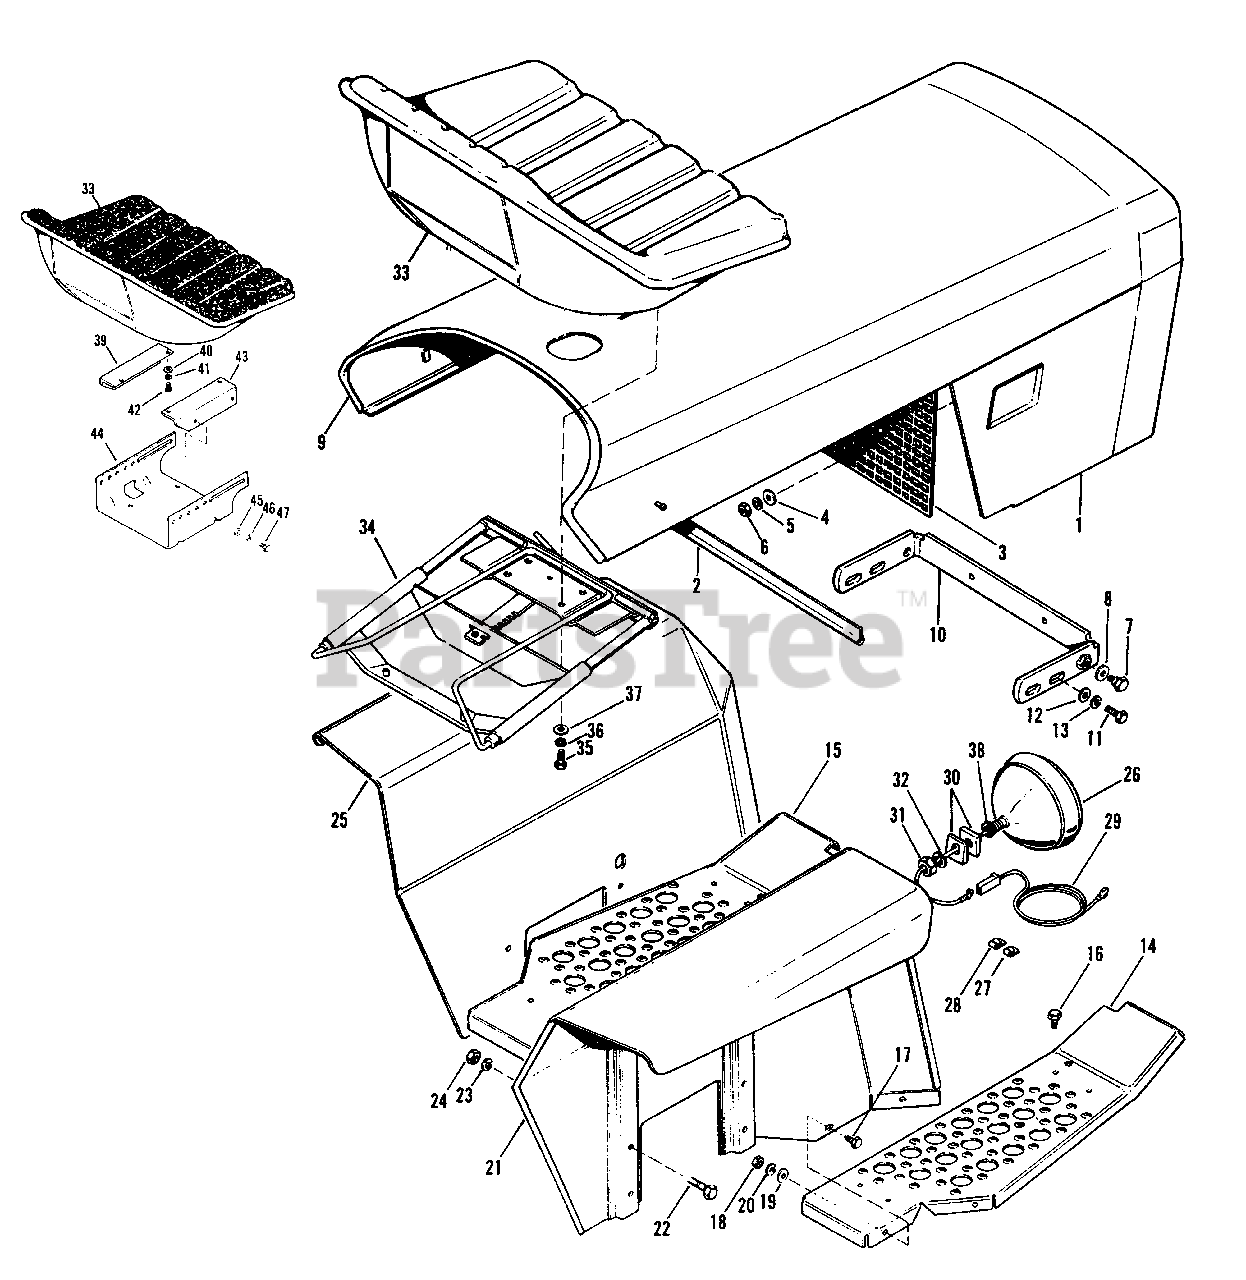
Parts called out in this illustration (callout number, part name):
1	Hood Assembly
3	Grille (Mfg. No. 920)
3	Grille (Mfg. Nos. 953 & 954)
5	Lockwasher, Shakeproof No. 10
6	Hex Nut, No. 10-24
7	Shoulder Bolt
11	Hex Capscrew, 3/8"-16 x 3/4" lg.
12	Plain Washer, 3/8"
13	Lockwasher, 3/8"
14	Platform, Right Hand
15	Platform, Left Hand
16	Thread Forming Screw, 5/16"-18 x 7/8" lg.
17	Thread Forming Screw, 5/16"-18 x 5/8" lg.
18	Hex Nut, 5/16"-18
19	Plain Washer, 1/4"
20	Locker, 5/16"
21	Wheel Guard Assy., R.H.
22	Hex Capscrew, 3/8"-16 x 1-1/2" lg.
23	Lockwasher, 3/8"
24	Hex Nut, 3/8"-16
25	Wheel Guard Assy., L.H.
30	Special Washer
31	Hex Nut, 1/2"-13
32	Lockwasher, 1/2"
33	Seat Assembly
34	Seat Adjuster (Mfg. Nos. 953 & 954)
35	Hex Capscrew, 5/16"-18 x 3/4" lg.
36	Lockwasher, 5/16"
37	Plain Washer, 5/16" (Mfg. Nos. 953 & 954)
38	Lockwasher, Shakeproof
39	Seat Bracket, L.H. (Mfg. No. 920)
40	Plain Washer, 5/16" (Mfg. No. 920)
41	Lockwasher, 5/16" (Mfg. No. 920)
42	Hex Capscrew, 5/16"-18 x 3/4" lg. (Mfg. No. 920)
43	Seat Bracket, R.H. (Mfg. No. 920)
44	Support (Mfg. No. 920)
45	Plain Washer, 3/8" (Mfg. No. 920)
46	Lockwasher, 3/8" (Mfg. No. 920)
47	Hex Capscrew, 3/8"-16 x 5/8" lg. (Mfg. No. 920)
